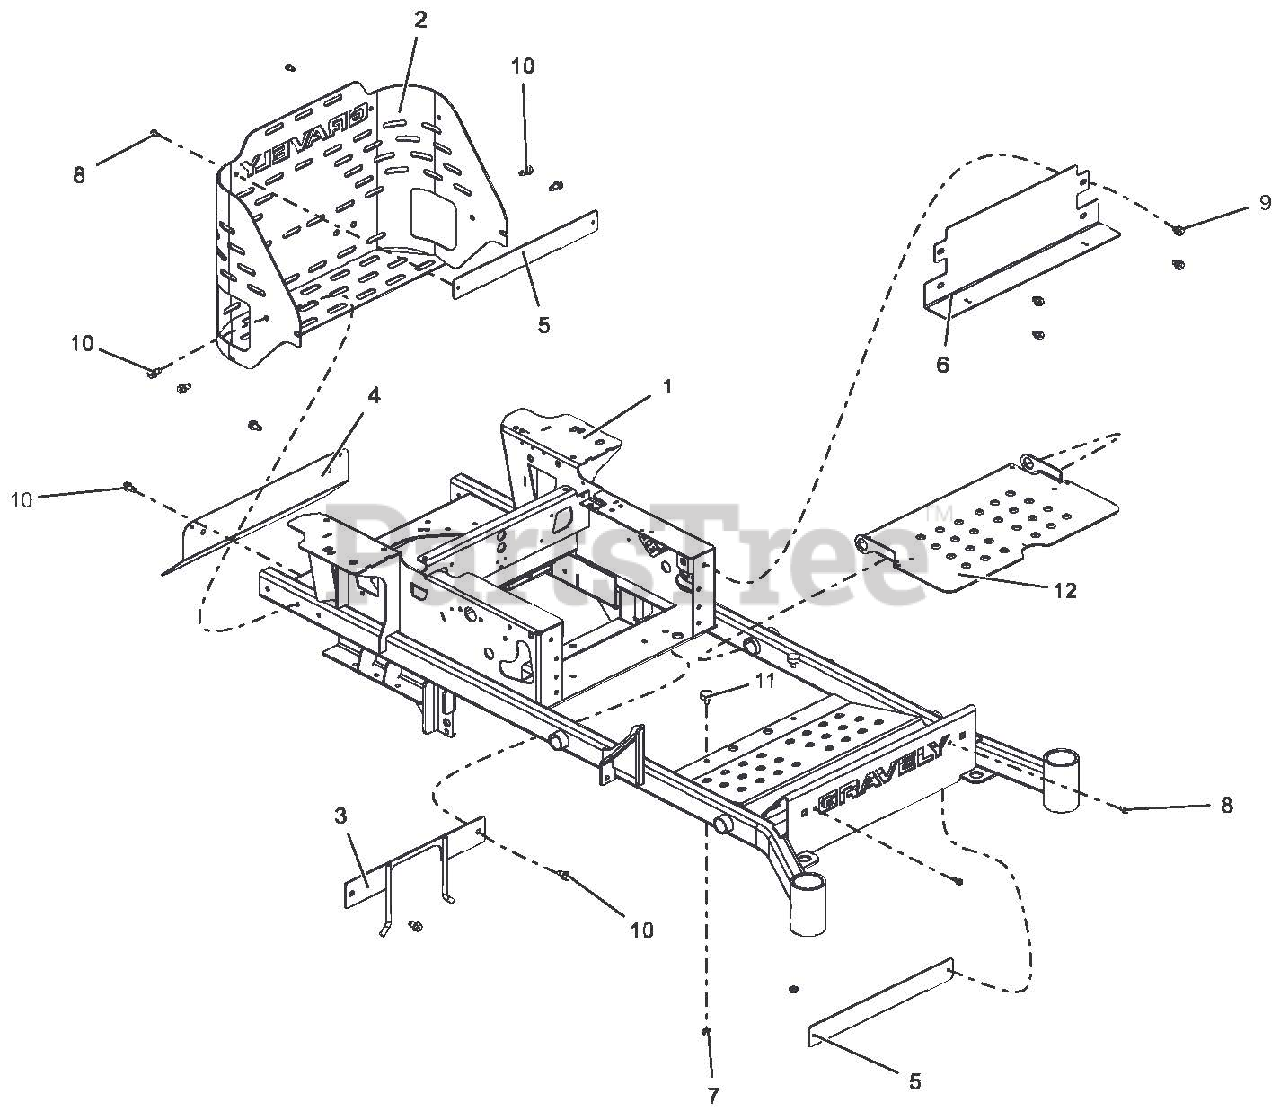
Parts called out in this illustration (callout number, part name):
1	48-52" MAIN FRAME W/SAFETY DECALS
2	REAR BUMPER W/SAFETY DECALS
3	WLDMT, PTO BELT FINGER-BLACK
4	SHIELD, MUFFLER HEAT
5	PLATE, BUMPER 2.00 X 16.50 - BLK
6	PLATE, PT/PT100 KICK-RED
7	@NUT-SPNLK-FLG .312-18 YWZC
8	SCR-TAP .25-20 X .50 HWH TR YWZ
9	SCR-TAP .38-16 X .50 HWH TR YWZ
10	SCR-TAP .38-16 X .75 HWH TR YWZ
11	BUMPER, RUBBER
12	FOOT, PLATE W/SAFETY DECALS
